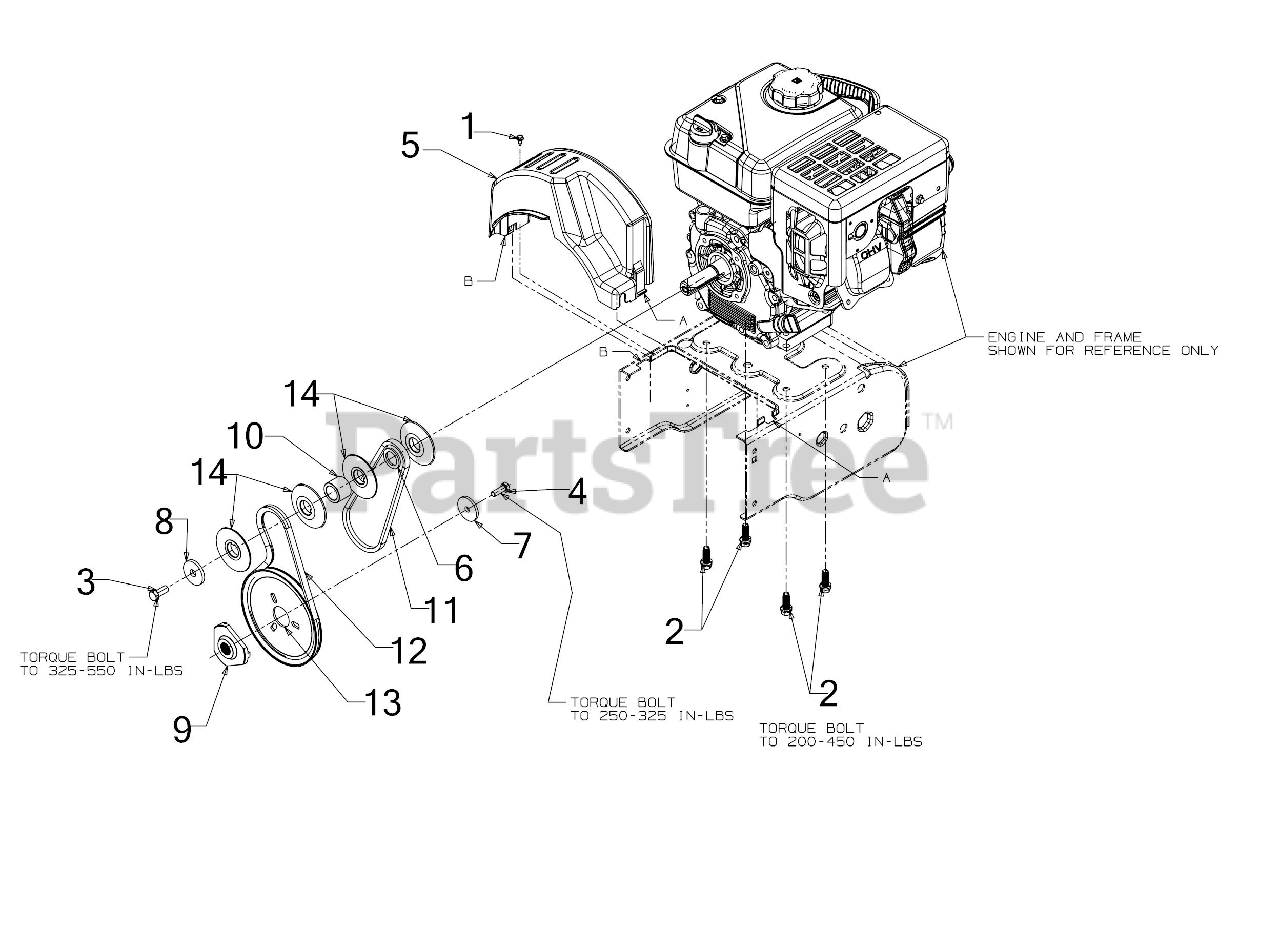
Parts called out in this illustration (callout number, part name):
1	HEX SCREW AB-TAP #10-16 x 0.500
2	SCREW 3/8-16 x 1
3	SCREW 3/8-NF x 7/8 - GR.5
4	SCREW 5/16-24 x .875 GR5
5	BELT COVER
6	FLAT WASHER
7	FLAT WASHER
8	FLAT WASHER .45 x 1.5 x .172 HT
9	ADAPTER PULLEY .75 DIA W/PINS
10	SPACER
11	BELT 3/8 x 21.1
12	V-BELT 3/8 x 26.375
13	AUGER PULLEY
14	HALF PULLEY-1/2 V
